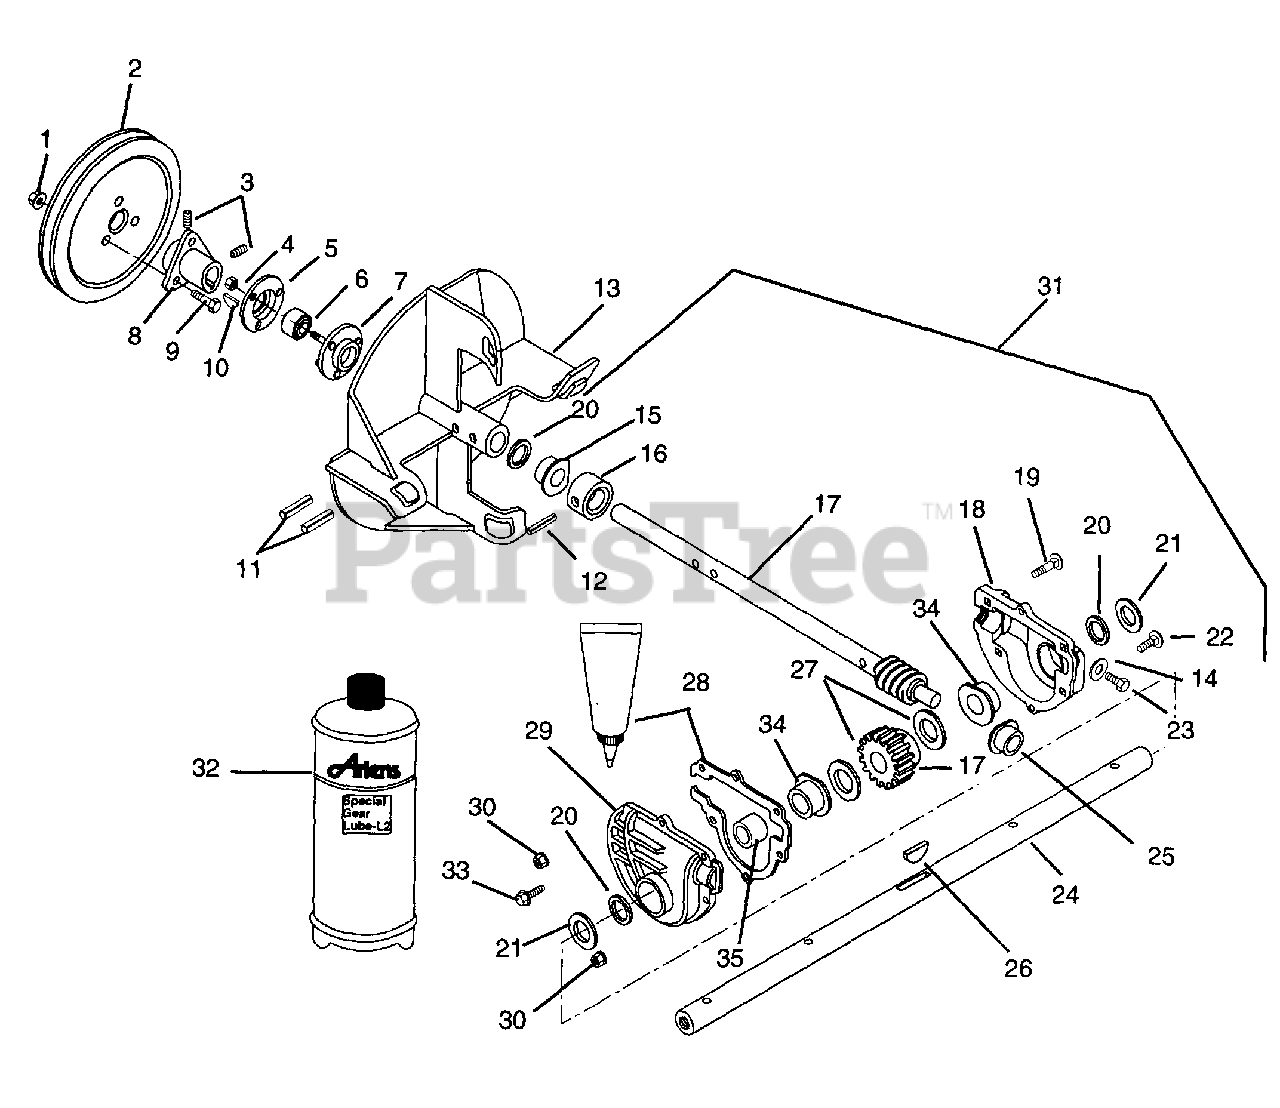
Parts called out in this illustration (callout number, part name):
1	@NUT-SPNLK-FLG .312-18 YWZC
2	PLY-V 8.50 X 1.25 3BLT
3	SCR-SET .31-18X.38 SKHCUPDL
4	@NUT-LK-CTR .25-20 YWZC
5	BEARING FLANGE
6	BRG-BALL .750X1.750X.50
7	BEARING FLANGE
8	HUB
9	BLT-SERRDHD SL .31-18X.75 YZ
10	KEY-WDRF .188X.875X.375 SAE11
11	PIN-ROLL .250X1.25
12	PIN-GRV .188X1.25 TP A
13	IMPELLER - 10"
14	WSHR-FIBER .437X.656X.032
15	BSHG-FLG .750X1.000X.750X1.250
16	THRUST COLLAR
17	SHAFT AND WORM GEAR ASSEMBLY
18	CASE, GEAR-LH-LARGE BORE-ALUM.
19	@BLT-RDHDSQNK .25-20X1.25 G5YZ
20	SEAL-OIL .750X1.375X.250
21	@WSHR-FL-STL.812X1.50X.135YWZC
22	BLT-RDHDSQSHK .25-20X.88 GR5YW
23	@SCR-TAP .38-16X.50 HWH TR YWZ
24	SHAFT, RAKE - 24"
25	BSHG-FLG .502X1X.750
26	KEY-WDRF .188X.625X.25 SAE 61
27	WSHR-HDND-THRST .755X1.40X.062
28	LOCTITE 518 GASKET--6ML TUBE
29	CASE, GEAR-RH-LARGE BORE-ALUM.
30	@NUT-SPNLK-FLG .25-20 YWZC
31	GEAR CASE - 24" - ALUMINUM
32	ARIENS 16 OZ.BOTTLE OF L2 LUBE
33	SCR-TAP 10-24X.75 HWH TR YWZC
34	BSHG-FLG .753X1.127X.500X1.501
35	BSHG-SLV .755X1.500X.442
